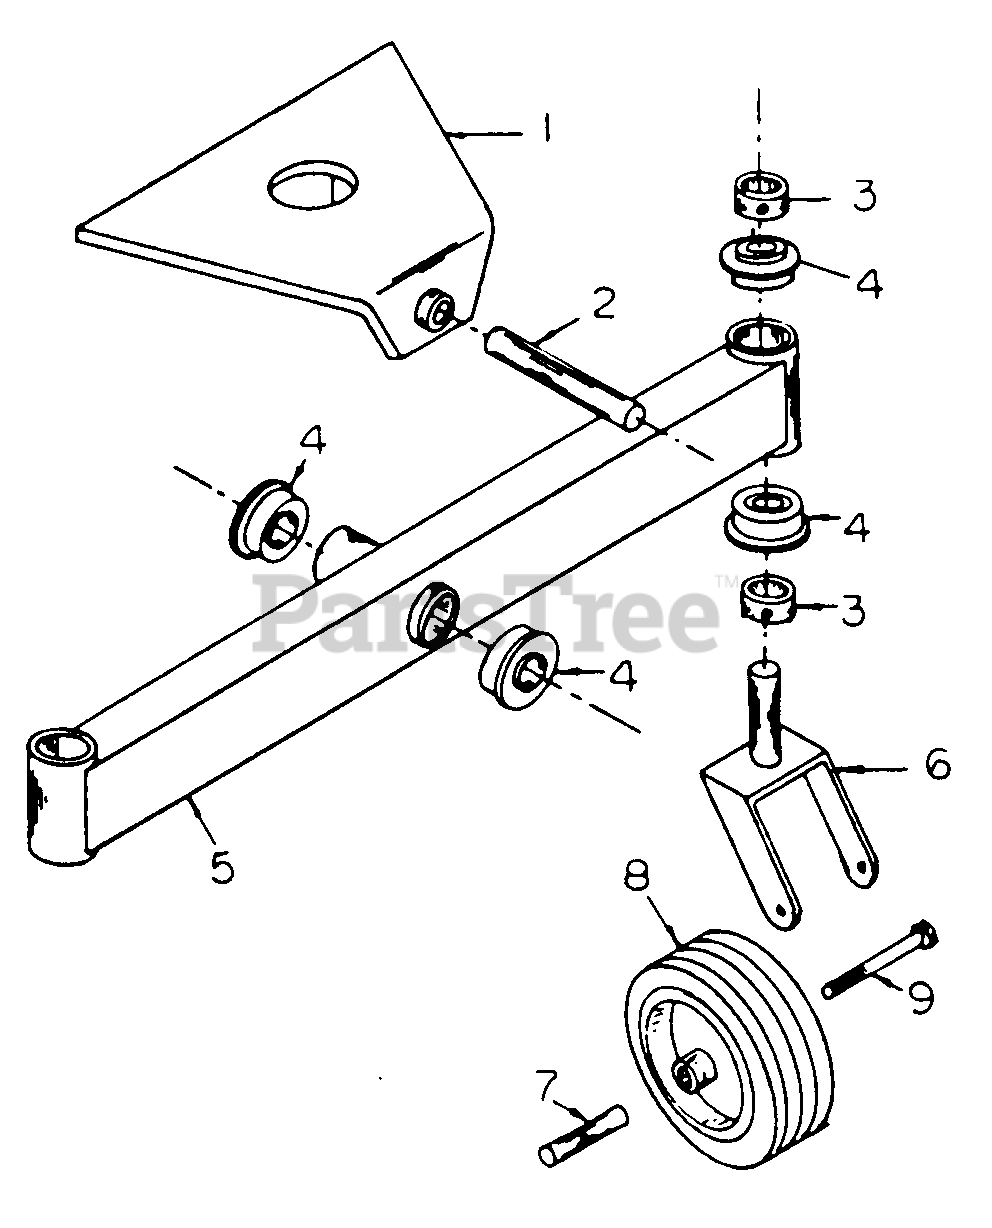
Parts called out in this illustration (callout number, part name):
1	Dusl Tail Wheel Mount
3	Set Collar, 1"
5	Dual Tail Wheel Axle
6	Dual Tail Wheel Fork
8	Wheel Assembly
9	Bolt, 1/2-13 x 6 1/2"
